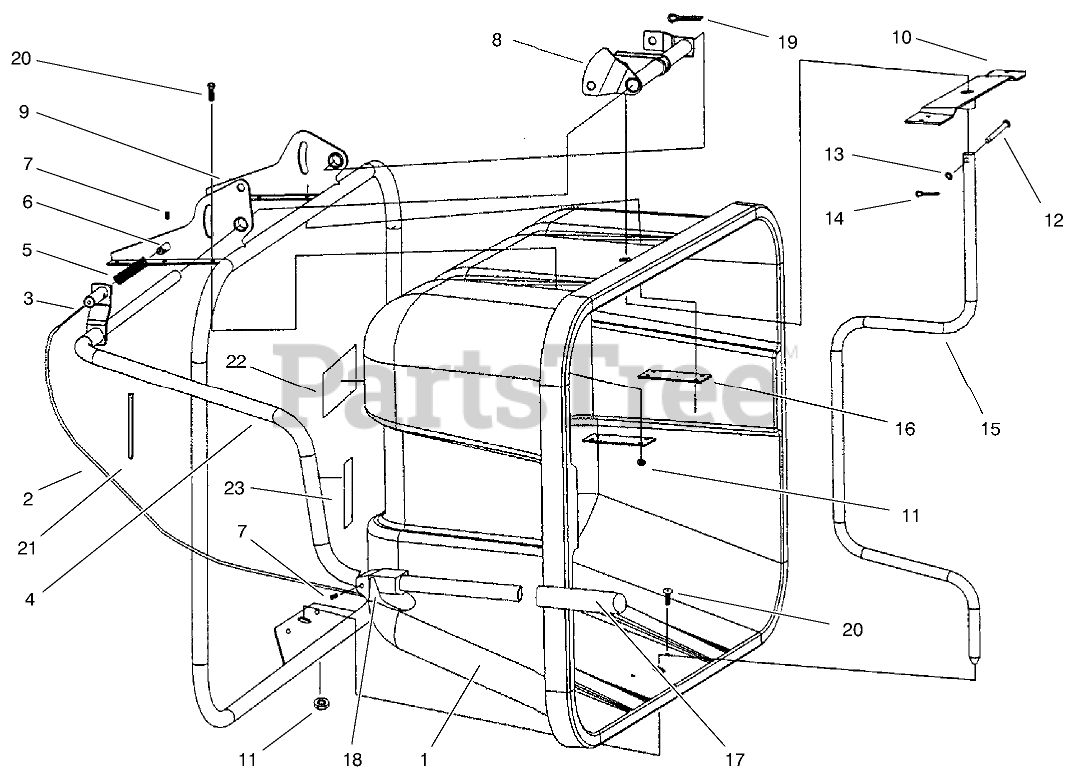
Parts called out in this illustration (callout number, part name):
1	HOPPER-BACK
2	SHIELD-CABLE
3	CABLE
4	Arm-Dump (Incl. Ref. #23)
5	SPRING
6	PIN-LOCK
7	SCREW-SET, HSH
8	LEVER
9	CHASSIS
10	GUIDE
11	NUT-HF
13	WASHER-PLAIN
14	PIN-COTTER
15	Rod-Locking
16	PLATE
17	GRIP-HANDLE
18	Lever Control Assembly (Incl. Ref. #2, 3, 7)
19	PIN-COTTER
20	SCREW-HEAD, TRUSS
21	TIE-CABLE
22	DECAL
23	LABEL-DUMP ARM OPERATION
